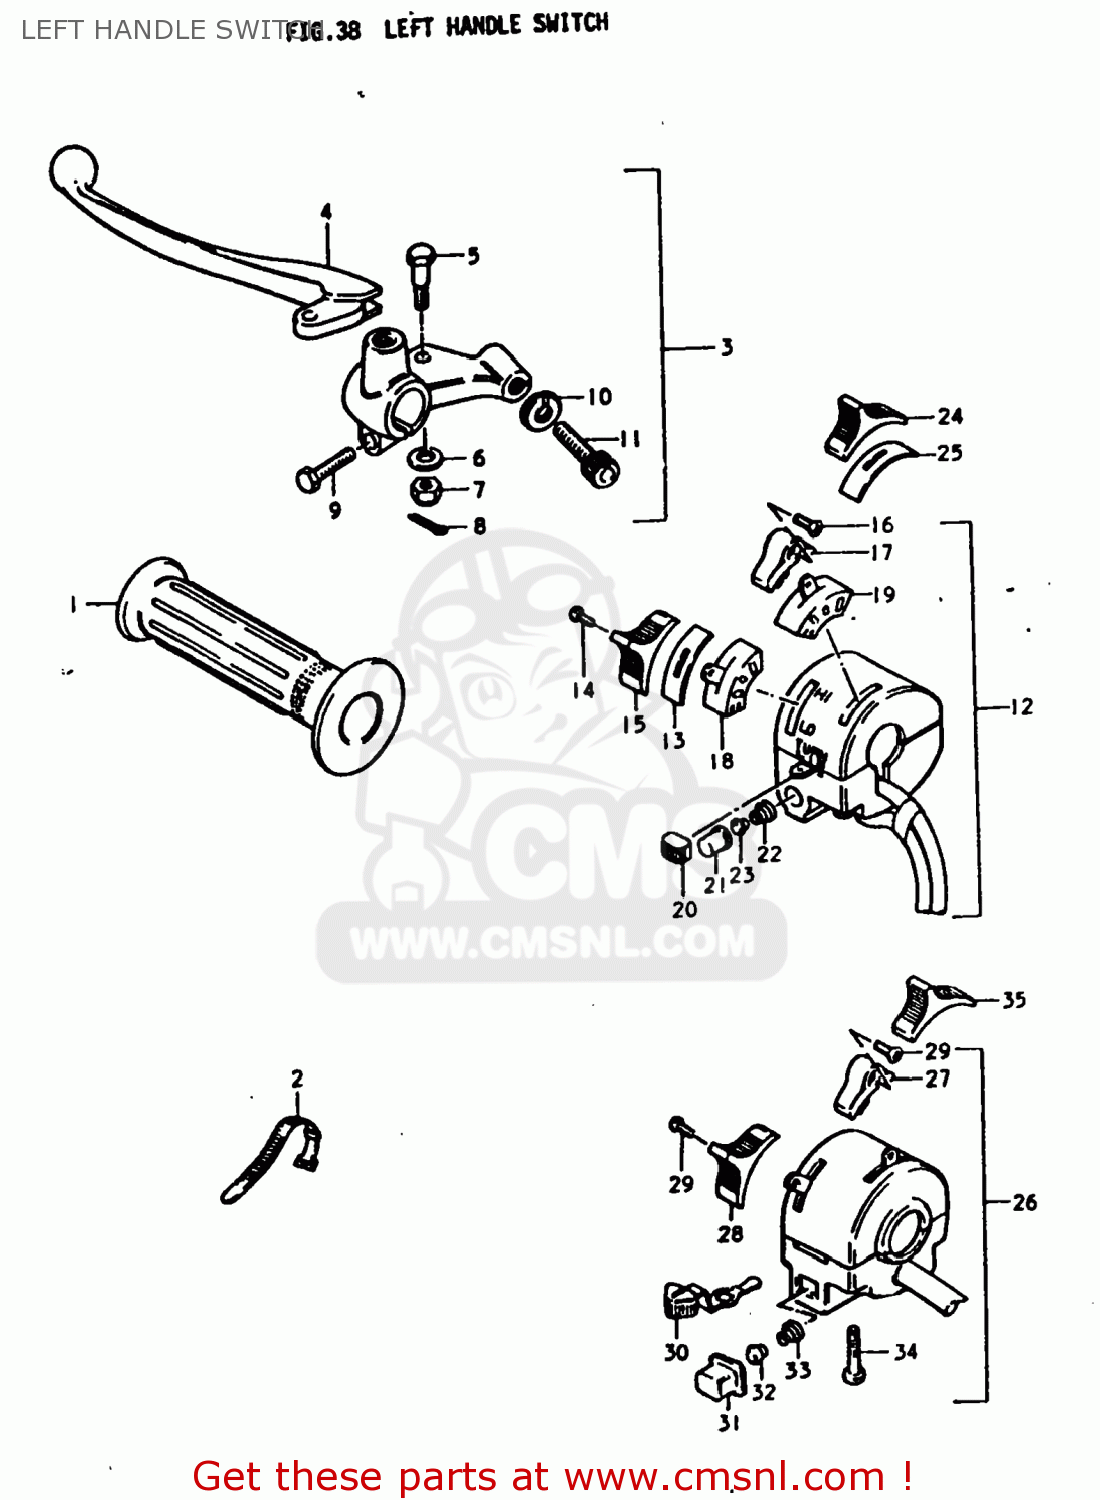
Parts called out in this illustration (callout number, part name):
1	GRIP,L
2	CLAMP(L:120)
3	LEVER ASSEMBLY
4	LEVER,CLUTCH
5	BOLT,LEVER
6	LOCK WASHER
7	NUT 6MM
8	COTTER PIN
9	BOLT
10	NUT,CABLE ADJUSTER
11	ADJUSTER,CABLE
12	SWITCH ASSEMBLY,HANDLE,LEFT
13	PLATE,DIMMER KNOB
14	SCREW, DIMMER
15	KNOB,HANDLE SWITCH,UPPER
16	SCREW
17	KNOB
18	SLIDING BLOCK, DIMMER SWITCH
20	KNOB,HANDLE SWITCH
21	BUTTON, HORN
22	SPRING,BUTTON
23	PLATE,HORN BUTTON
24	KNOB,HANDLE SWITCH
25	PLATE,LIGHTING KNOB
26	SWITCH ASSEMBLY,HANDLE,LEFT
27	KNOB,STOP
28	KNOB,DIMMER SWITCH
29	SCREW
30	KNOB,TURNSIGNAL
31	BUTTON,HORN
32	CONTACT
33	SPRING
34	SCREW
35	KNOB,LIGHTING SWITCH
